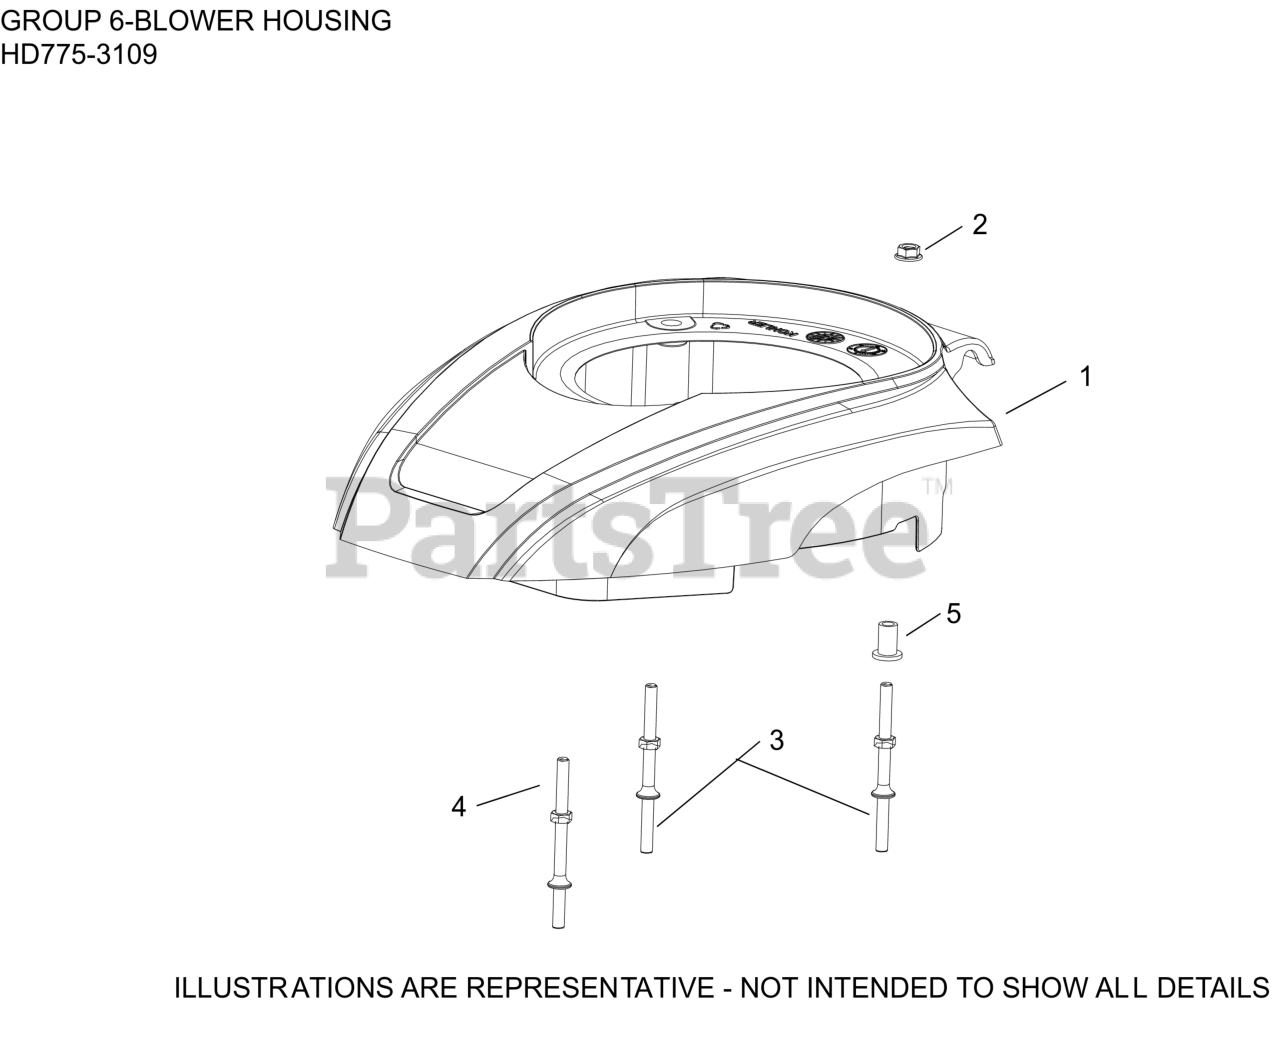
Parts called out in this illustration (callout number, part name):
1	COVER, ENGINE
2	NUT, HEX FLANGE (M6) - USE 14 100 16-S
3	STUD-USE 14 072 25-S
4	STUD-USE 14 072 26-S
